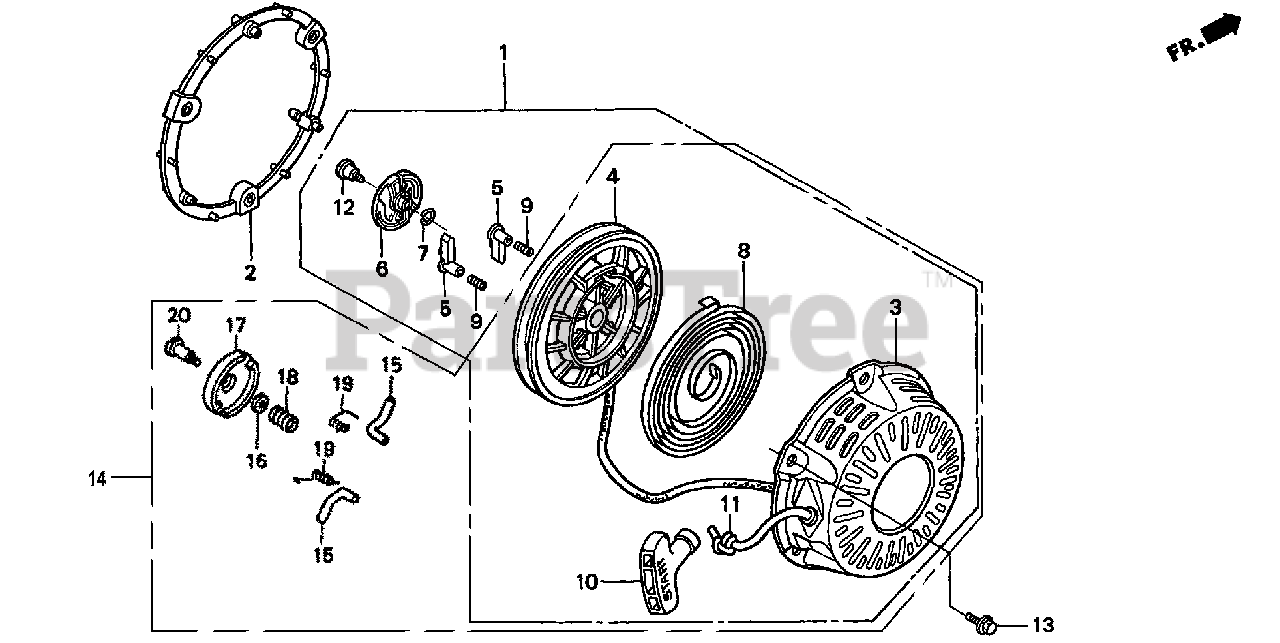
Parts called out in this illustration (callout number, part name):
1	STARTER ASSY., RECOIL *R280* (POWER RED)
2	SPACER, RECOIL STARTER MOUNTING *R280* (POWER RED)
3	CASE, RECOIL STARTER *R280* (POWER RED)
4	REEL, RECOIL STARTER
5	RATCHET, STARTER
6	GUIDE, RATCHET
7	SPRING, FRICTION
8	SPRING, RECOIL STARTER
9	SPRING, RETURN
10	KNOB, RECOIL STARTER
11	ROPE, RECOIL STARTER (#5X55")
12	SCREW, SETTING
13	BOLT, FLANGE (6X18)
14	STARTER ASSY., RECOIL *R280* (POWER RED)
15	RATCHET, STARTER
16	PLATE, FRICTION
17	GUIDE, RATCHET
18	SPRING, FRICTION
19	SPRING, RETURN
20	SCREW, SETTING
